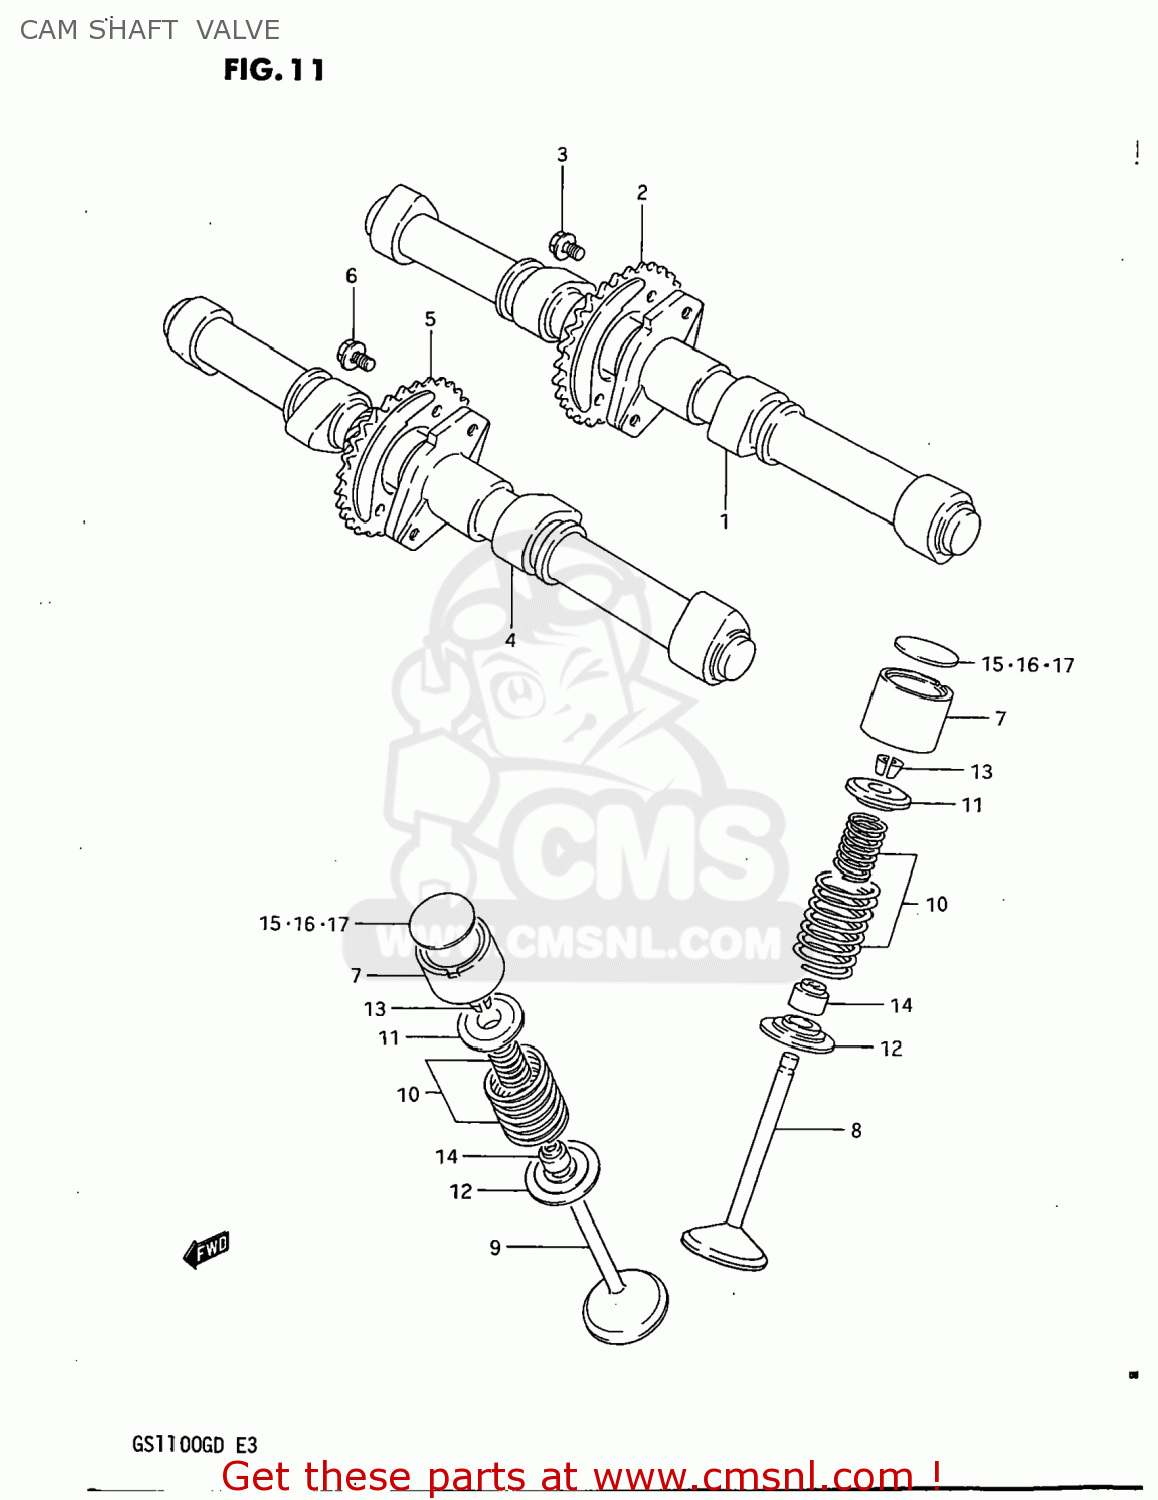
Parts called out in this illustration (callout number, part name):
1	CAMSHAFT,INTAKE
2	SPROCKET,INTAKE CAMSHAFT
3	BOLT(7X11)
4	CAMSHAFT,EXHAUST
5	SPROCKET,EXHAUST CAMSHAFT
6	BOLT(7X11)
7	TAPPET
8	VALVE,INTAKE
9	VALVE,EXHAUST
10	SPRING SET,VALVE
11	RETAINER,VALVE SPRING
12	SEAT,VALVE SPRING
13	COTTER VALVE
14	SEAL,OIL(7X14.4X9)
15	SHIM,TAPPET
16	SHIM,TAPPET
17	SHIM,TAPPET
18	SHIM SET,TAPPET
19	CASE
